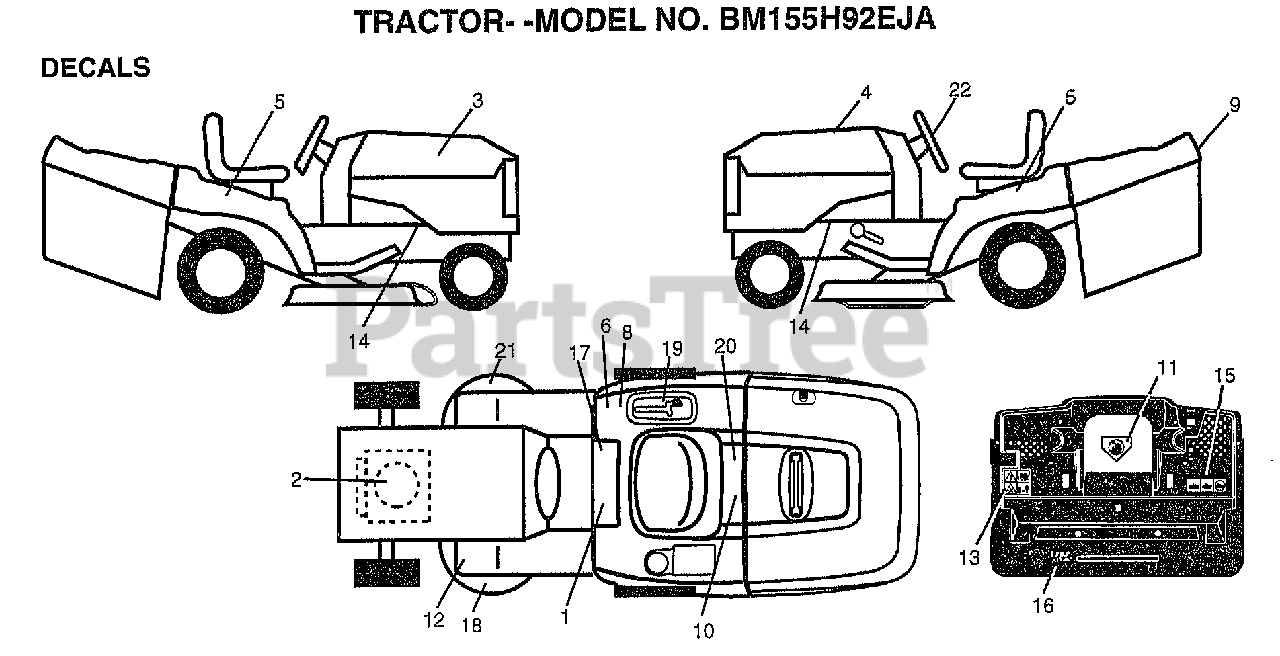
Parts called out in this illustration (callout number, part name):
1	DECAL.READ.O.MANU
3	DECAL.HOOD.RH
4	DECAL.HOOD.LH
5	"DECAL-FENDER,AUTO"
8	DECAL.EURO.ST.CE.
9	DECAL.FEND.BESTGR
10	DECAL.BATRY.3-3908
11	DECAL.DANGER.CUTF
12	DECAL-BRAKE/CLUTC
13	DECAL.WARNING.BACKPLATE.CRD
14	"DECAL CHASSIS,HOT"
15	DECAL, OPER BAG
16	DECAL.DRAWBAR.LDL
17	DECAL BRAK PARK
18	"DECAL,ENVIRO DECK"
19	DECAL.BYPASS.FENDER.CRD.
20	DECAL.BYPASS.FENDER.CRD.LT.YT
21	DECAL.DECK.HEX.BELT
22	DECAL.STRG.WHL
